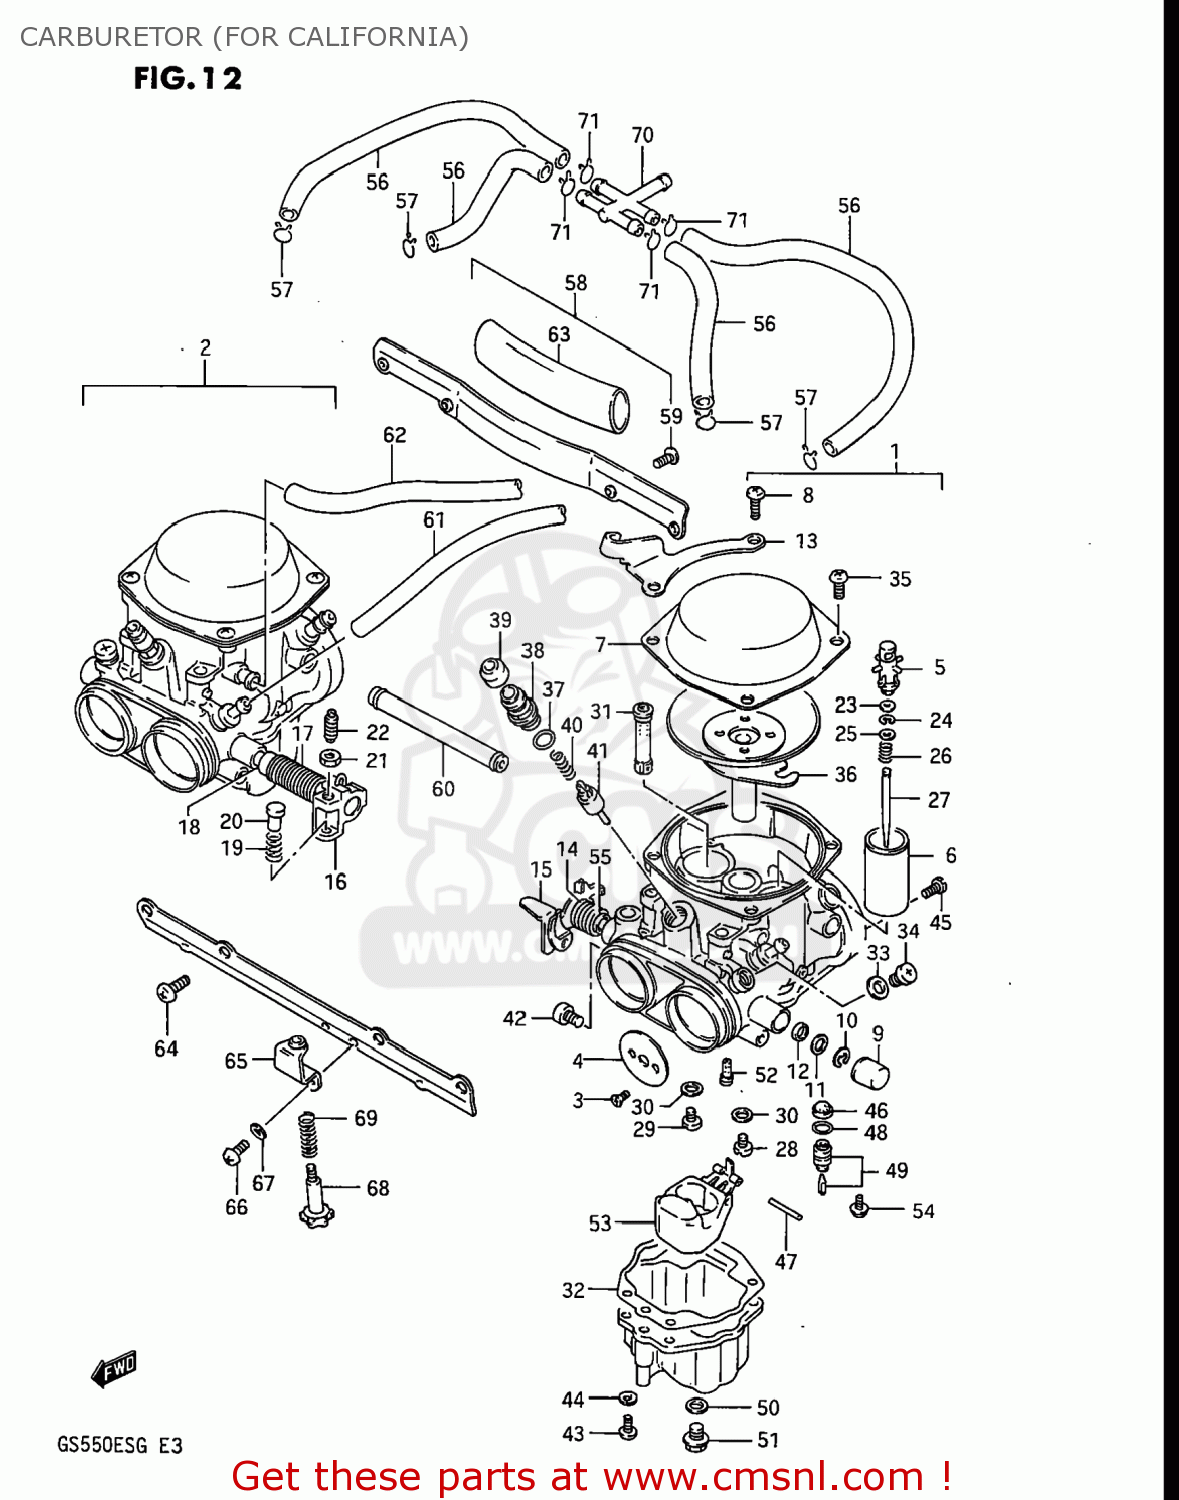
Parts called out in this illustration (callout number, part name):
1	CARBURETOR ASSEMBLY
2	CARBURETOR ASSEMBLY
3	SCREW
4	VALVE,THROTTLE
5	HOLDER,GUIDE
6	VALVE,THROTTLE
7	COVER,DIAPHRAGM
8	SCREW
9	CAP,THROTTLE SHAFT
10	E RING
11	GASKET,THROTTLE SHAFT (NAS)
12	SEAL
13	BRACKET,THROTTLE CABLE
14	SPRING,THROTTLE SHAFT
15	SHAFT ASSEMBLY
16	SHAFT ASSEMBLY
17	SPRING
18	RING
19	SPRING,THROTTLE SCREW
20	PIN,THROTTLE LEVER
21	NUT
22	SCREW
23	RING
24	CAP,LEVER
25	WASHER
26	SPRING
27	NEEDLE JET
28	JET,MAIN(95)
29	JET,MAIN
30	WASHER,NEEDLE NOZZLE
31	JET,NEEDLE
32	GASKET,FLOAT CHAMBER (MCA)
33	WASHER
34	SCREW
35	SCREW
36	DIAPHRAGM,CARBURETOR
37	O RING
38	HOLDER,GUIDE
39	CAP
40	SPRING
41	VALVE,STARTER
42	SCREW
43	SCREW
44	LOCK WASHER
45	JET
46	FILTER
47	PIN,FLOAT
48	O-RING,NEEDLE VALVE
49	VALVE ASSEMBLY,NEEDLE
50	GASKET (NAS)
51	PLUG,DRAIN
52	JET,PILOT(37.5)
53	FLOAT
54	SCREW
55	RING,THROTTLE SHAFT
56	HOSE
57	CLIP
58	FLANGE ASSEMBLY,CARBURETOR
59	SCREW
60	PIPE,CARBURETOR
61	HOSE 4.5X8X390
62	HOSE
63	HOSE(16X19X100)
64	SCREW
65	BRACKET,SLOW ADJUST
66	SCREW
67	WASHER,LOCK
68	ADJUSTER
69	SPRING
70	SPRING
71	CLIP
